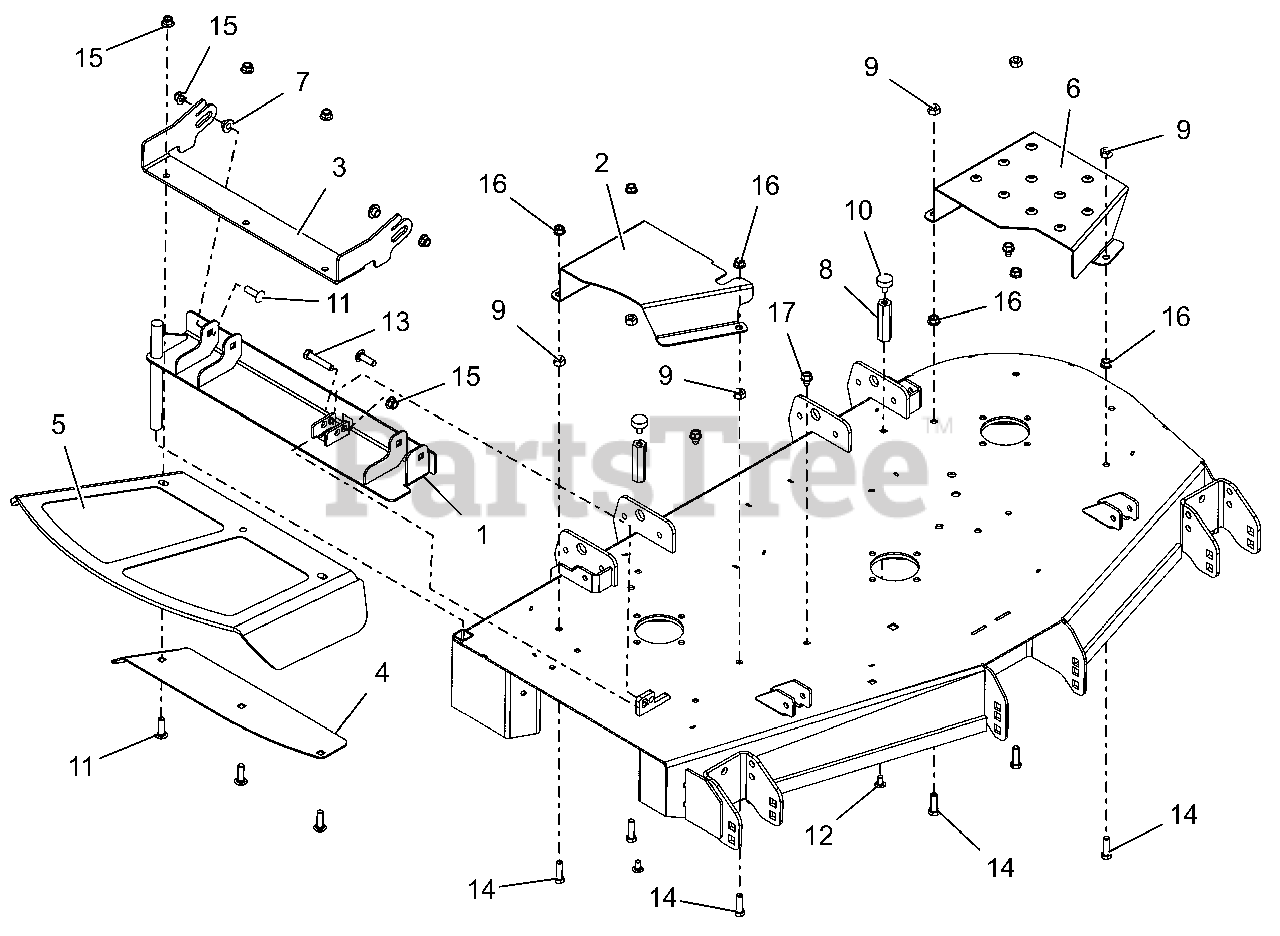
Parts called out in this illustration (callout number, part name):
1	48-60 DISCH CHT MTG WMT W/SAFE
2	GUARD,PRO-TURN DECK RH BELT-RD
3	48-60" CHUTE MTG BRKT - RED
4	48-60 DISCH CHUTE CLMP PLT-RED
5	CHUTE,48-60" FRMD RUBBER DISCH
6	GUARD,PRO-TURN DECK LH BELT-RD
7	BSHG-FLG .385X.500X.875X.406
8	NUT, COUPLING .31-18 2.75 LG
9	NUT-HEAVY HEX .38-16 YWZC
10	BUMPER, RUBBER
11	@BLT-RHDSSQNK .38-16X1.25 G5YZ
12	BLT-RDHDSQSHNK.31-18X.62 YZ-LK
13	@BLT-HEX .38-16X2.00 GR5 YWZC
14	@BLT-HEX .38-16X1.25 GR5 YWZC
15	@NUT-LK-NYL-FLG .38-16 YWZC
16	@NUT-SPNLK-FLG .375-16 YWZC
17	@SCR-TAP .38-16X.50 HWH TR YWZ
